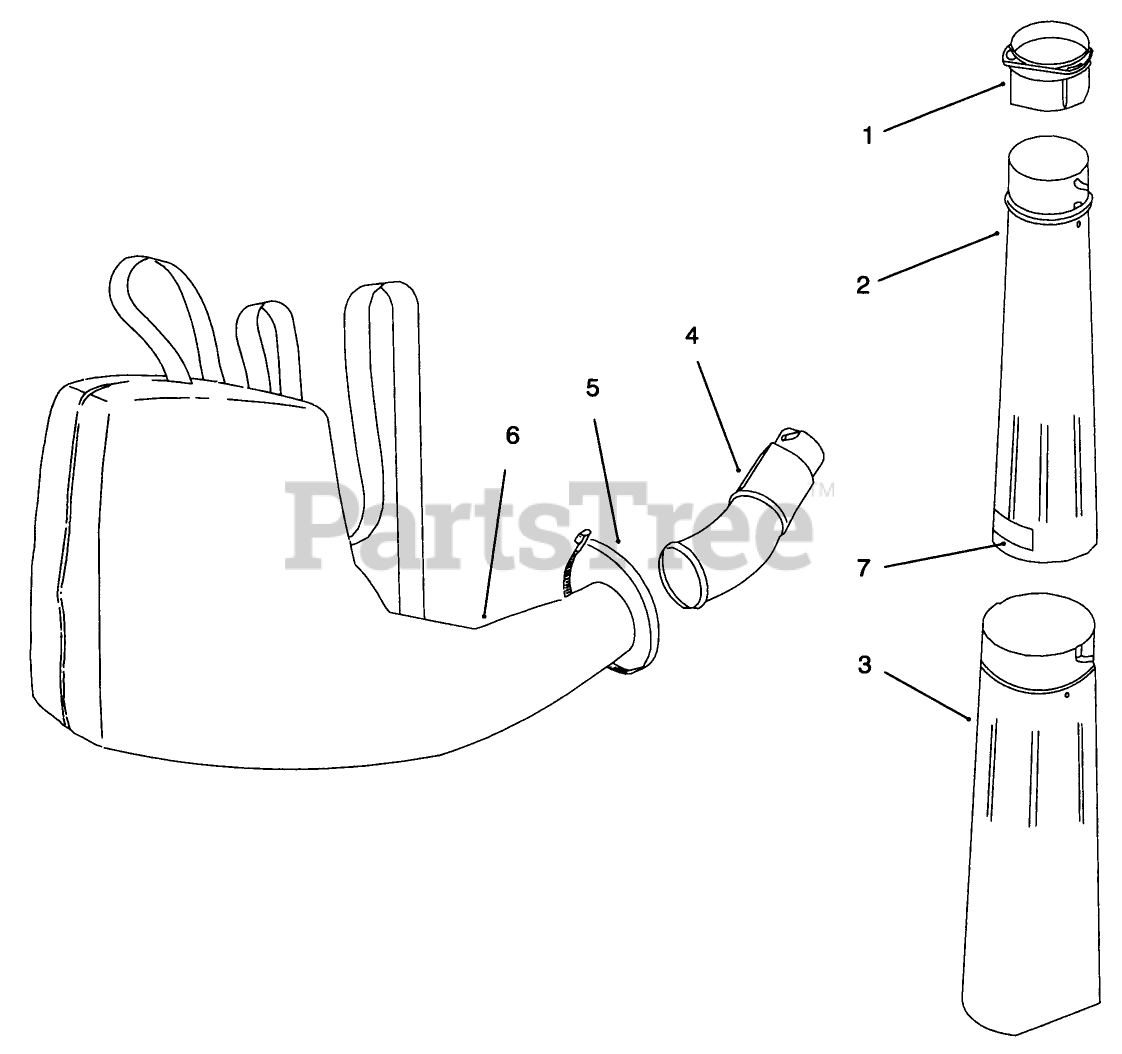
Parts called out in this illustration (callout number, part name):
2	VACUUM-UPPER TUBE/ADAPTER
3	TUBE - LOWER VACUUM
6	ASSEMBLY - VACUUM BAG
7	DECAL - WARNING
